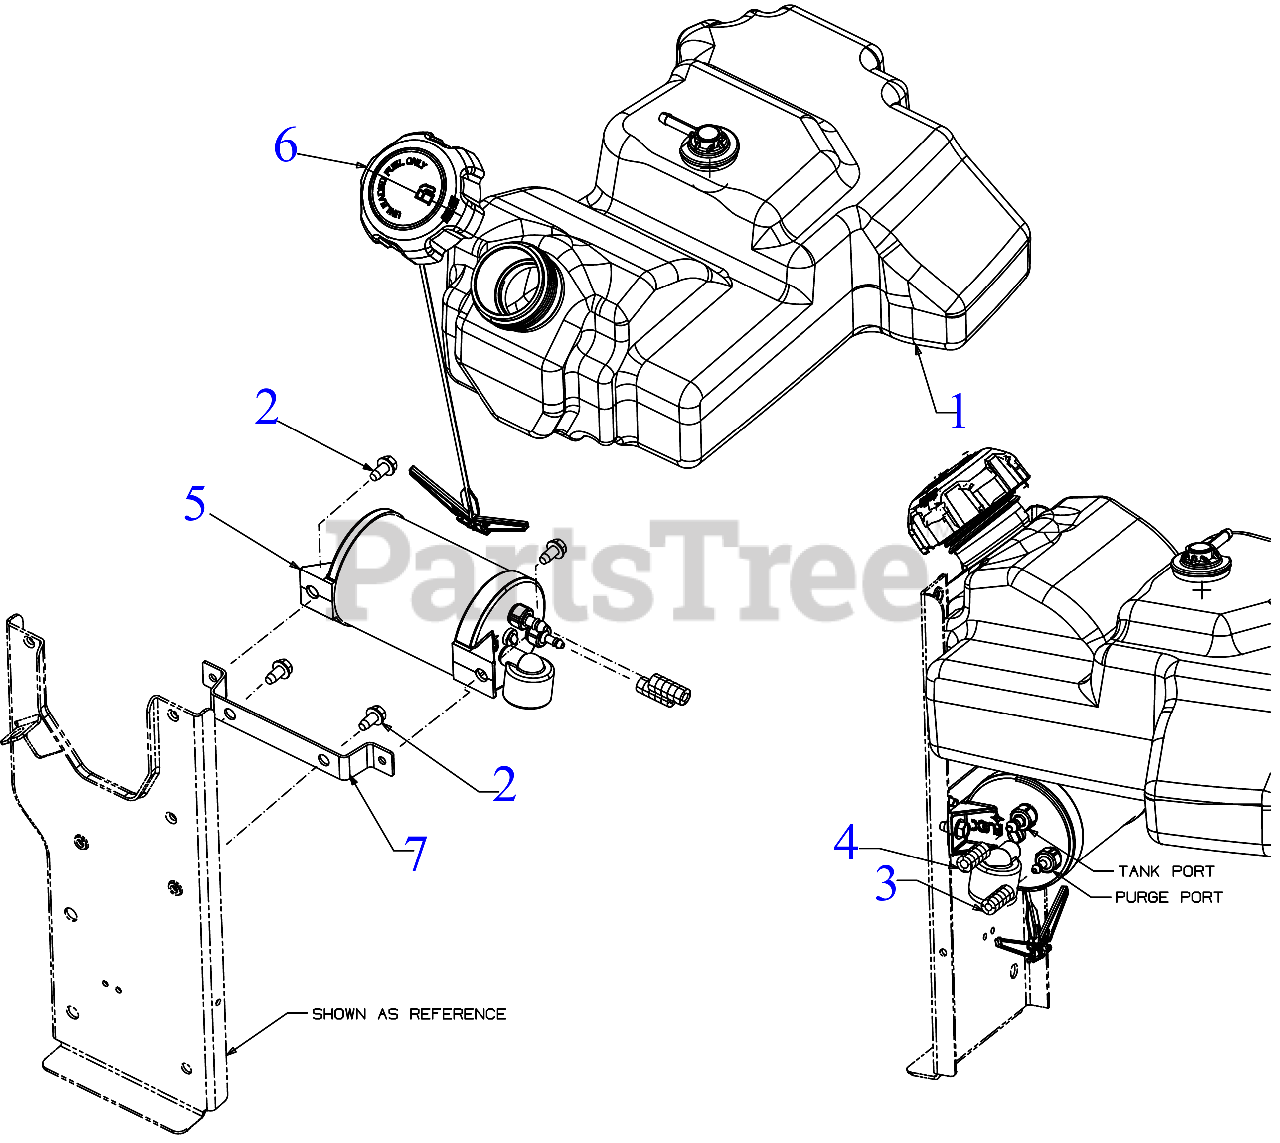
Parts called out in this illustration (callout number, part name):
1	FUEL TANK ASSEMBLY 1 GAL
2	SCREW 1/4-20 X.500
3	FUEL HOSE LO PERMEATION 22"
4	FUEL HOSE LO PERMEATION 28"
5	CARBON CANISTER
6	FUEL CAP (W/TETHER)
